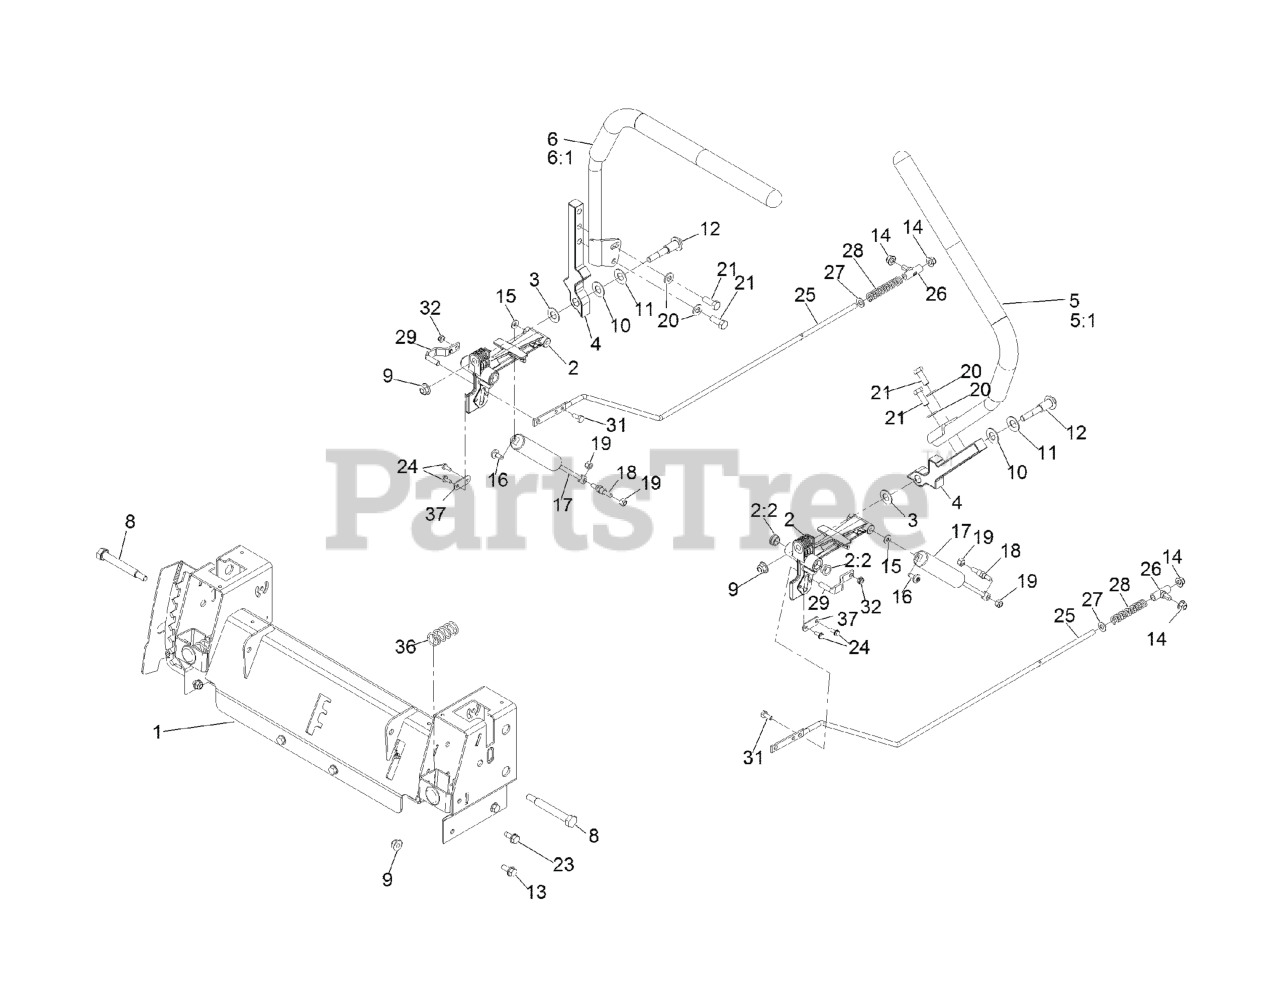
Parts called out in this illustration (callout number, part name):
1	CONTROL-BOX
2	ACTUATOR ARM ASM
2:2	BUSHING-FLANGE
3	WASHER-NYLON
4	ARM-CONTROL
5	HANDLE-CONTROL, LH
6	HANDLE-CONTROL, RH
8	BOLT-PIVOT
9	NUT-HF, NI
11	WASHER-BELLEVILLE
12	BOLT-PIVOT
13	SCREW-HHF
14	NUT-HF, NI
16	SCREW-SHOULDER
18	STUD-DAMPER
19	NUT-LOCK, NI
20	WASHER-FLAT
21	SCREW-HH
23	Screw-HWH 5/16-18 X 3/4 Tf
24	SCREW-TAPTITE
25	Screw-HWH #10-24 X 1/2 Taptite
26	Screw-HWH #10-24 X 1/2 Taptite
26	Rod-Hydro
27	WASHER-PLAIN
28	SPRING-RETURN, NEUTRAL
29	PIN-ROD, HYDRO
31	SCREW-HH
32	NUT-LOCK, NI
36	SPRING-RETURN
37	PLATE-STOP, HYDRO
